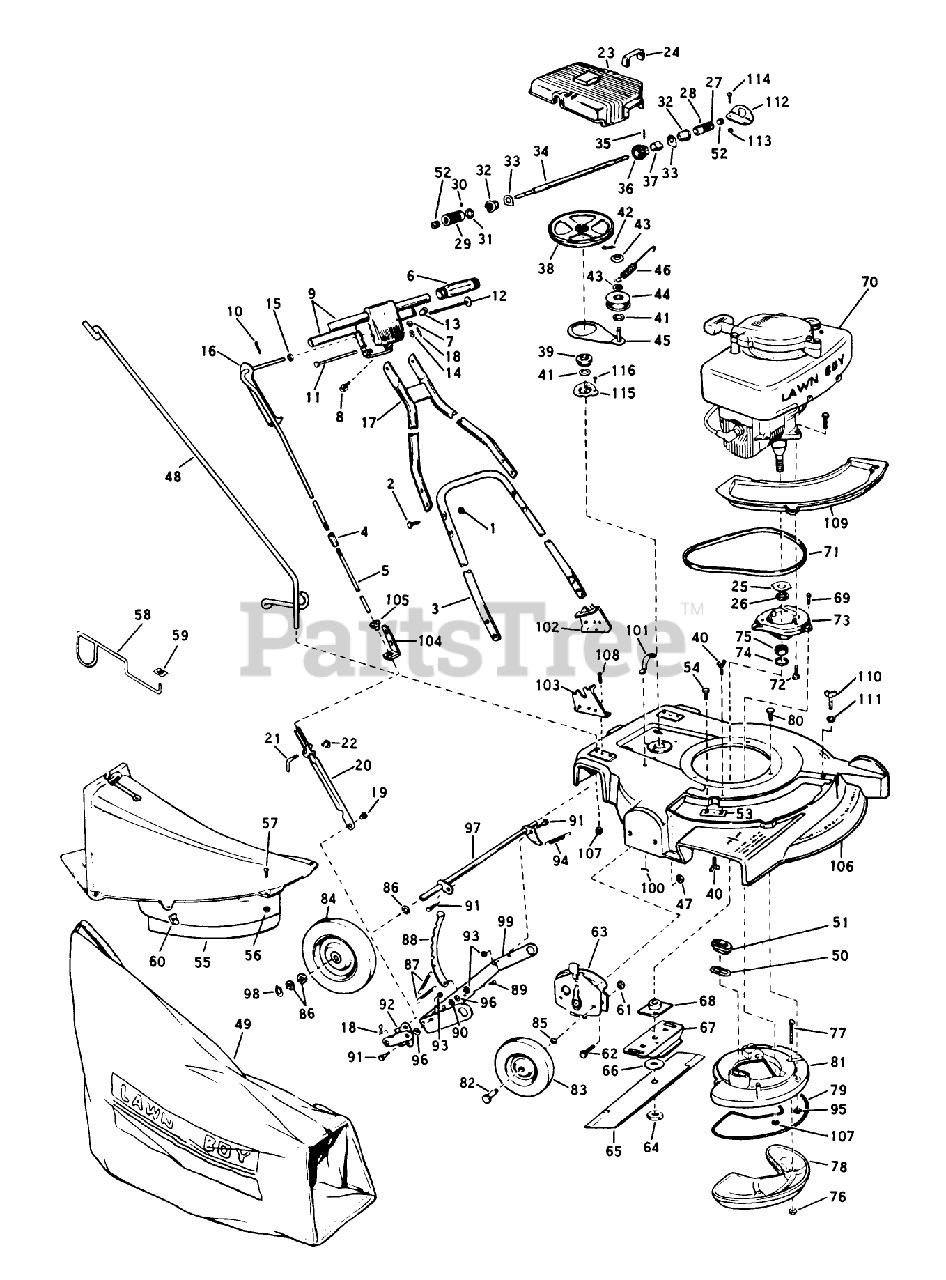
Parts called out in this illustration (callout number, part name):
10	Pin-Cotter
38	PULLEY&OILER FELT (13)
44	Idler Pulley Brg. Assy.
49	89802 LB WHOLE GOODS
50	GASKET S
52	GREASE PLUG
55	Chute Skirt Assembly (Includes Hardware)
60	SPEED NUT ARDEN
64	NUT-BLADE
68	PLATE AND COLLAR ASM
76	LOCKNUT E
82	BOLT WHEEL
85	WASHER WROUGHT
91	BOLT RB&W
93	STOP NUT
96	WASHER S
98	RETAINING RING
108	SCREW S
